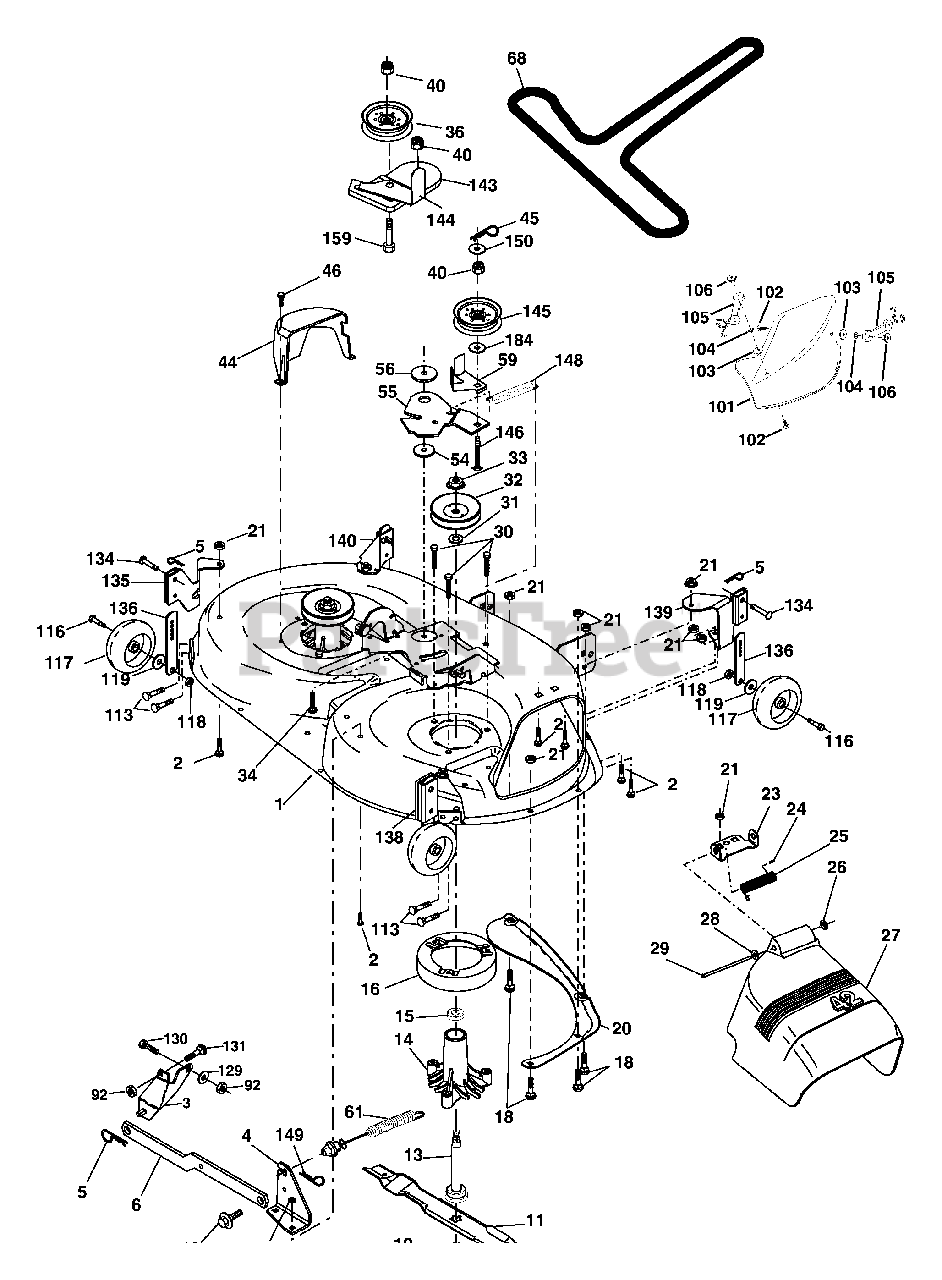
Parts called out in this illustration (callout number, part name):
1	Mower Deck Assembly, 42"
2	Bolt
3	Bracket Asm Fr. Sway Bar 3/42
4	Bracket Asm Deck 42" Sway Bar
5	Retainer Spring
6	Bar Sway Deck
9	Washer, Lock
10	Washer, Hardened
11	Blade Mower 42" Hi-Lift
11	Blade, Mulching 42" Std
11	Blade Mulching 42" Premium
13	Shaft Assembly, Mandrel, Vented
14	Housing, Mandrel, Vented
15	Bearing, Ball, Mandrel
16	Stripper, Mandrel Deck
18	Bolt, Carriage 5/16-18 x 5/8
19	Bolt, Shoulder
20	Baffle, Vortex
21	Nut
23	Bracket, Deflector Mower 42"
24	Cap, Sleeve 80 x 112 Blk Mower
25	Spring, Torsion, Deflector 2 52
26	Nut, Push Phos & Oil
27	Shield, Deflector 42" Blk
28	Washer 11/32 x 5/8 x 16 Ga.
29	Rod, Hinge 42" 6 75 W/G
30	Screw Thdrol
31	Washer, Spacer Mower Vented
32	Pulley, Mandrel
33	Nut, Toplock
34	Bolt Carr SH 3/8-16 x 1-1/2 Gr.5
36	Pulley, Idler, Flat
40	Nut Lock 3/8-16
44	Guard, Mandrel, LH
45	Retainer
46	Screw, Thdrol 1/4-20 x 5/8 T
54	Washer, Hardened
55	Arm, Idler
56	Spacer, Retainer
59	Guard TUV Idler
61	Spring Ext Elect. Clutch
68	V-Belt, 42" Mower
92	Nut Lock Hex w/Ins 3/8-16 unc
101	Mulcher Cover
102	Screw, Pan Hd Phillip 10-24 x 5/8
103	Washer, Flat
104	Washer, Lock
105	Latch Assembly
106	Nut, Weld
113	Screw 5/16-18 x 3/4
116	Bolt, Shoulder
117	Wheel, Gauge
118	Nut Centerlock 3/8-16
119	Washer 3/8 x 7/8 x 14 Ga.
129	Washer 13/32 x 13/16 x 12 Ga.
130	Bolt Fin HEx 3/8-16 unc x 1 Gr. 5
131	Bolt RDHD SQNK 3/8-16 unc x 1
134	Pin Head Rivet
135	Bracket Asm. Whl Ga. R LH
136	Bar Adjusting Gauge Wheel
138	Bracket Asm Whl Ga. R RH
139	Bracket Asm. Whl Ga. F RH
140	Bracket Asm Whl Ga. F LH
143	Bracket Arm Idler 42"
144	Keeper Belt 42" Clutch Cable
145	Pulley Idler Flat
146	Bolt Carriage Idler
148	Spring Return Idler
149	Retainer Spring Yellow
150	Washer 9/32 x 3/4 x 10 Ga.
159	Bolt Rdhd Sqn 3/8-16 unc x 1-3/4
184	Washer 13/32 x 7/8 x 10 Ga.
